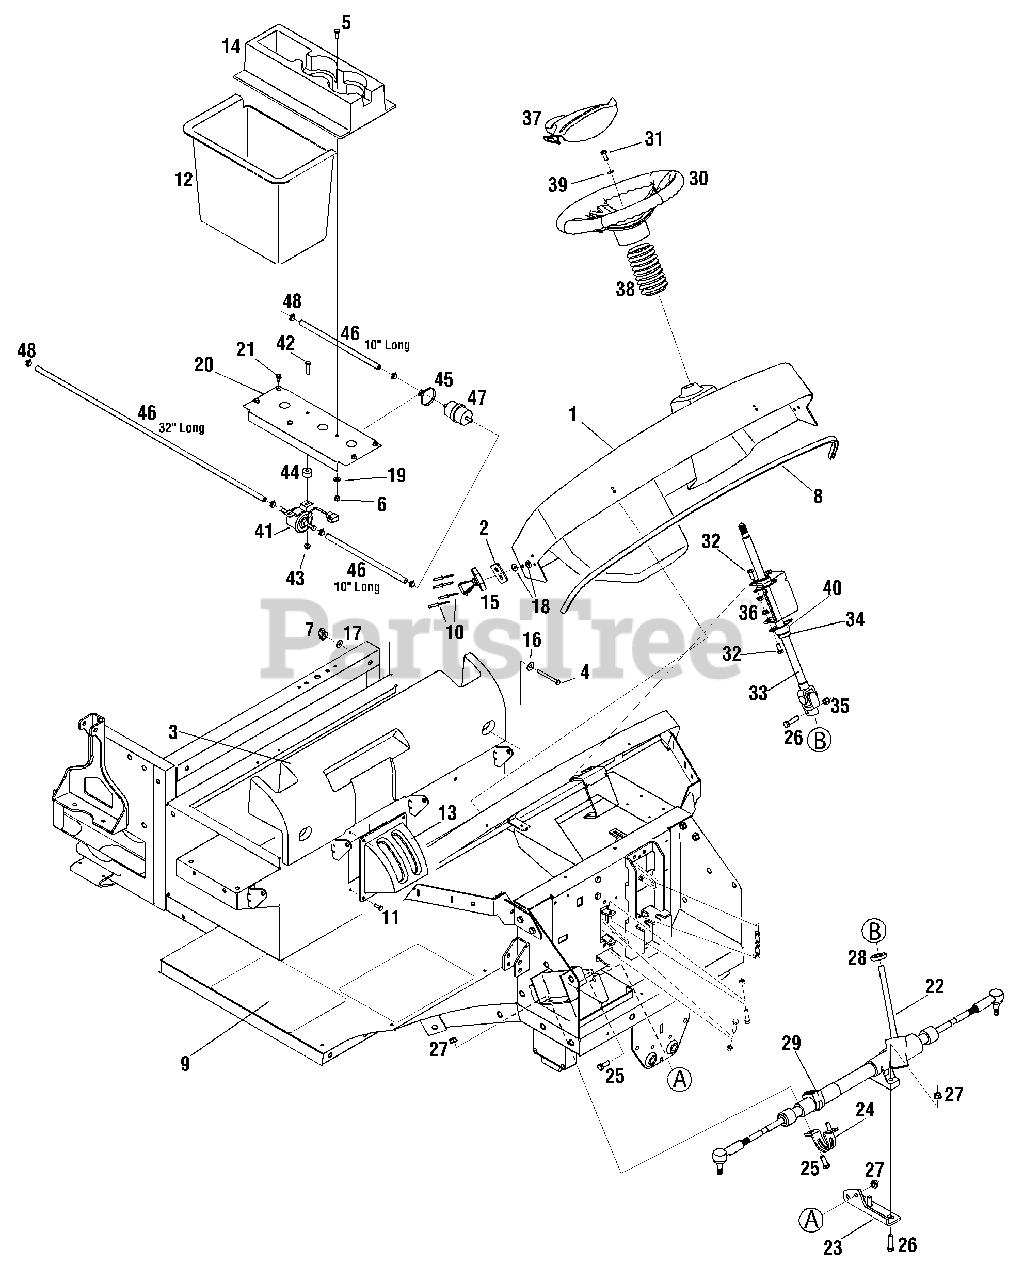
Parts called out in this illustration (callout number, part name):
1	Dash Assembly
2	Hood Mounting Plate
3	Panel, Airbox Cover
4	Hex Screw, 1/4-20 x 2.75
5	Hex Screw, 1/4-20 x .75, Gr5
6	Hex Lock Nut, Nylon, 1/4-20
7	Wing Nut, 1/4-20
8	Trim, Bulb Seal, 1/4
9	Foot Pad, Abrasive
10	Rivet, Pop, .187
11	Rivet, Pop, .188
12	Container, Bulkhead
13	Panel, Shift Cover
14	Console, Cup Holder
15	Handle, Latch
16	Flat Washer, 349 x .875 x .04
17	Washer, Flat, .28 x .74 x .063
18	Washer, Flat, .194 x .62 x .063
19	Washer, Flat, .25 x .630 x .0515
22	Gear Assembly, Steering
25	Hex Screw, 3/8-16, 1.00, Gr5
26	Hex Screw, 3/8-16, 1.50, Gr5
27	Nut, Flange Lock, 3/8-16
28	Grommet, Steering Shaft
29	Bushing, Rubber
30	Wheel, Steering
31	Hex Screw, 5/16-18, .75, Gr5, Patch
32	Hex Screw, 5/16-18, .75, Gr5
33	Shaft, Steering, 5/8 Spline
34	Collar, .75
35	Nut, Hex Lock Nylon, 3/8-16
36	Nut, Flange Lock, 5/16-18
37	Cover, Steering Wheel
38	Bellow, Steering, 4.75 Lg
39	Washer, Flat, .344 x .688 x .065
40	Bearing, Flange, .75 ID, Self-Aligning
41	Pump Assembly, Fuel
42	Hex Screw, 1/4-20 x 1.25
43	Flange Lock Nut, 1/4-20
44	Bushing, .96OD x .50
45	Cable Tie
46	Fuel Line Hose
47	Fuel Filter
48	Clamp, Hose
